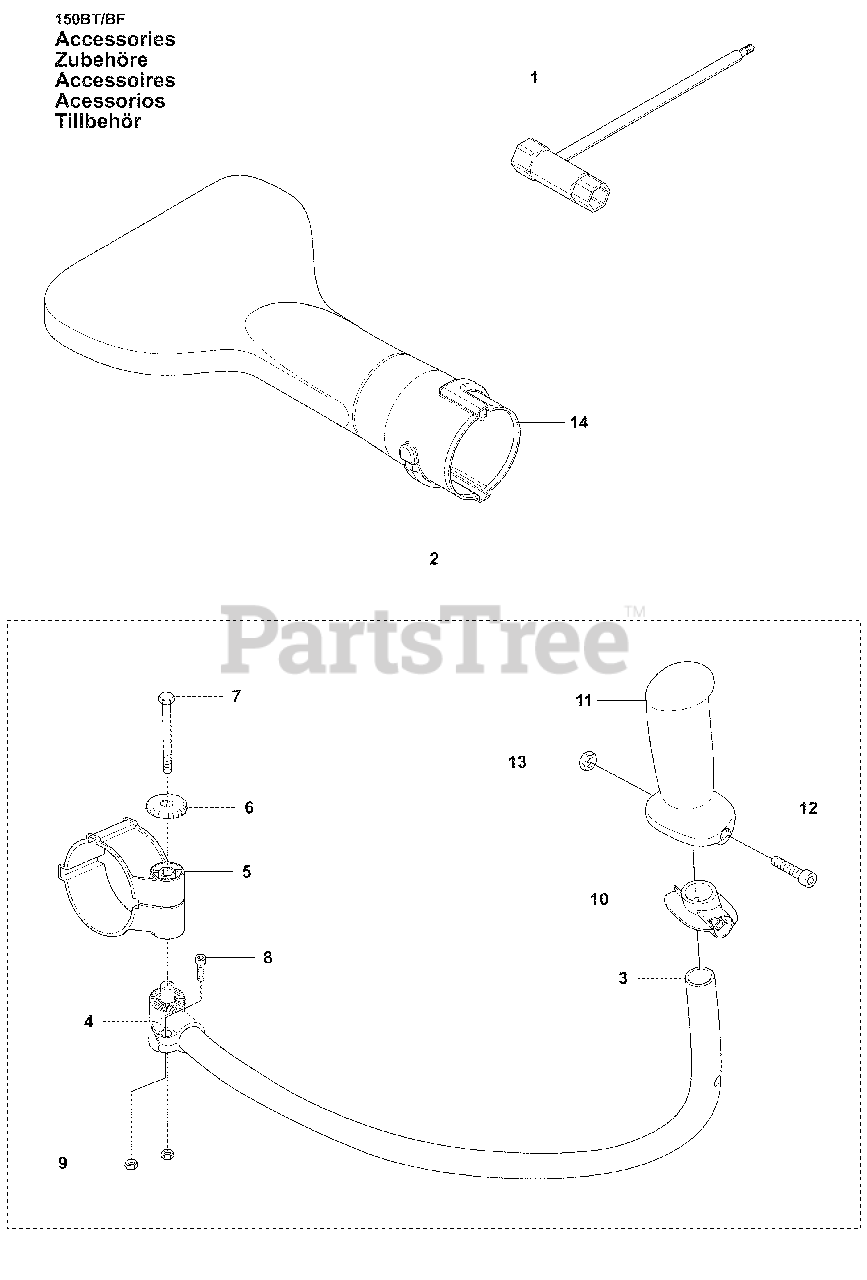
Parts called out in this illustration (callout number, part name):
1	SOCKET
2	HANDLEBAR ASSY
5	HOLDER TH
8	SCREW MC6S 5X10
14	FLAT NOZZLE
